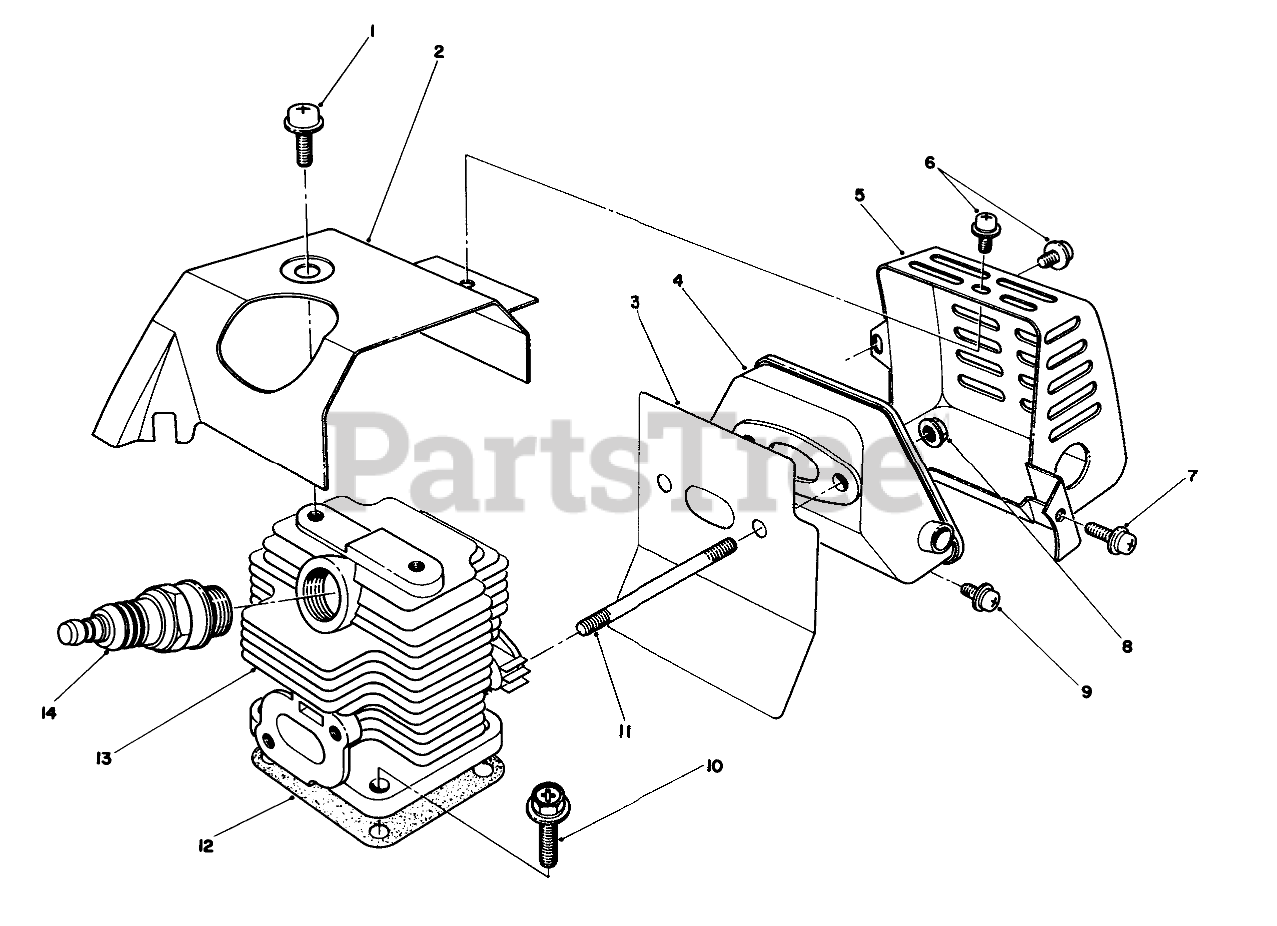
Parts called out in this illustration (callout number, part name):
1	Screw & Dishes
2	CYLINDER COVER
3	Gasket-Muffler
4	MUFFLER
5	COVER, MUFFLER
6	Screw & Washer
7	Screw & Washer
8	NUT, FLANGE
9	Screw & Washer
10	BOLT AND WASHER
11	Bolt-Stud
12	CYLINDER GASKET
13	Cylinder (Incl. Ref. #11)
14	SPARK PLUG (NGK)
